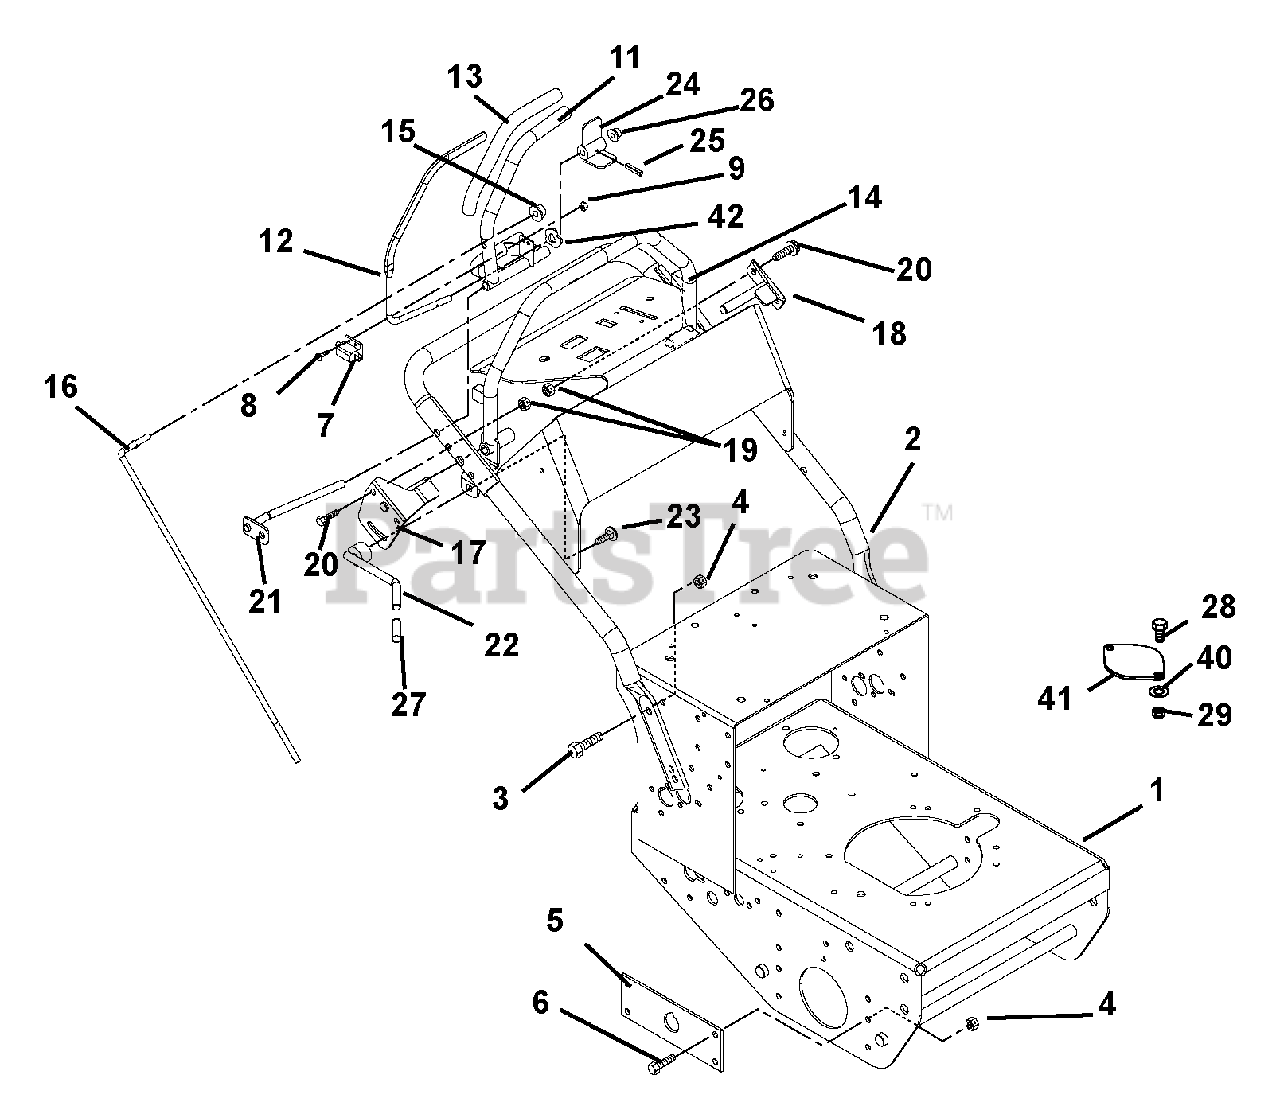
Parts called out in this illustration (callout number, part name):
1	KIT-FRAME W/DECALS
2	KIT-HANDLEBAR/DECALS HR15-ERGO
2	KIT-HANDLEBAR/DECALS HE17-ERGO
2	KIT-HANDLEBAR/DECAL GR13/15-PS
3	@BLT-HEX .38-16X1.00 GR5 YWZC
4	@NUT-LK-NYL .38-16 YWZC
5	BRACKET, WHEEL MOTOR LH
5	BRACKET, WHEEL MOTOR RH
5	BRKT, WHEEL MOTOR LH
5	BRKT, WHEEL MOTOR RH
5	PLATE, SUPPORT
6	@BLT-HEX .38-16X1.00 GR5 YWZC
7	SWITCH- DOUBLE POLE N.O./N.O.
7	SWITCH- SINGLE POLE N.O.
7	SWITCH,INTERLOCK
8	@SCR-MCH 10-24X.75 HWH YWZC
9	@NUT-LK-NYL 10-24 W/INSRT YWZC
11	WMT-LEVER-RH SPEED CONTROL-HYD
11	WMT-LEVER-LH SPEED CONTROL-HYD
11	WMT-LEVER-RH SPEED CONTROL-GR
11	WMT-LEVER-LH SPEED CONTROL-GR
12	LEVER - OPERATOR PRESENCE
13	GRIP - HANDLEBAR
14	WMT - SPEED CONTROL STOP
15	RG-RTNG-EXT .375X.010
16	ROD - STEERING - HYDRO
16	ROD - STEERING
17	WMT-CONTROL STOP LIMITER-RH
17	WMT - CONTROL STOP LIMITER -RH
18	WMT-CONTROL STOP LIMITER-LH
19	@NUT-LK-TOP-FLG .31-18 YWZC
20	@BLT-HEX .31-18X1.75 GR5 YWZC
21	WMT - SPEED CONTROL PIVOT - RH
21	WMT - SPEED CONTROL PIVOT - LH
22	LEVER - CONTROL STOP LOCK
23	BLT-RDHDSQSHK.31-18X.75 GR2 YW
23	@BLT-RDHDSQNK .38-16X.75 G5YZ
24	ACTUATOR - SWITCH
25	PIN-ROLL .125X.75
26	NUT-PUSH .312
27	GRIP,HAND CLUTCH LEVER
28	@BLT-HEX .38-16X.75 GR5 YWZC
29	@NUT-LK-TOP-FLG .38-16 YWZC
40	@WSHR-FL-STL.406X.812X.065 YWZ
41	PLATE, COVER
42	WAVE WASHER .390X.655X.110
